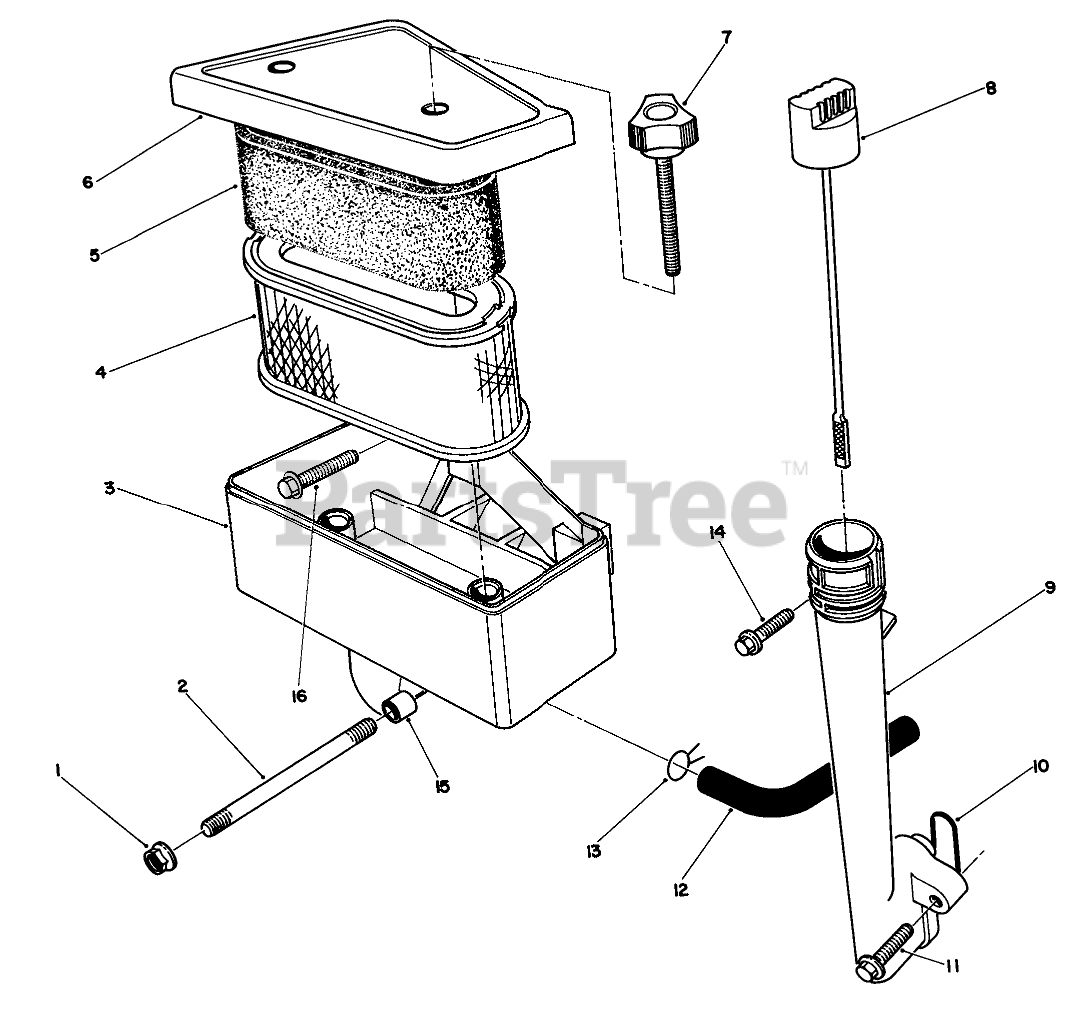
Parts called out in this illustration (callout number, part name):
3	AIR CLEANER BODY
4	Air Filter Assembly (Incl. Ref. #5)
5	Filter-Foam
6	AIR CLEANER COVER B
7	RETAINER - COVER
8	DIPSTICK
10	O-RING
13	CLAMP F/W ENGINE
15	SPACER
16	HEX FL HD M.6X1.0X25MM
